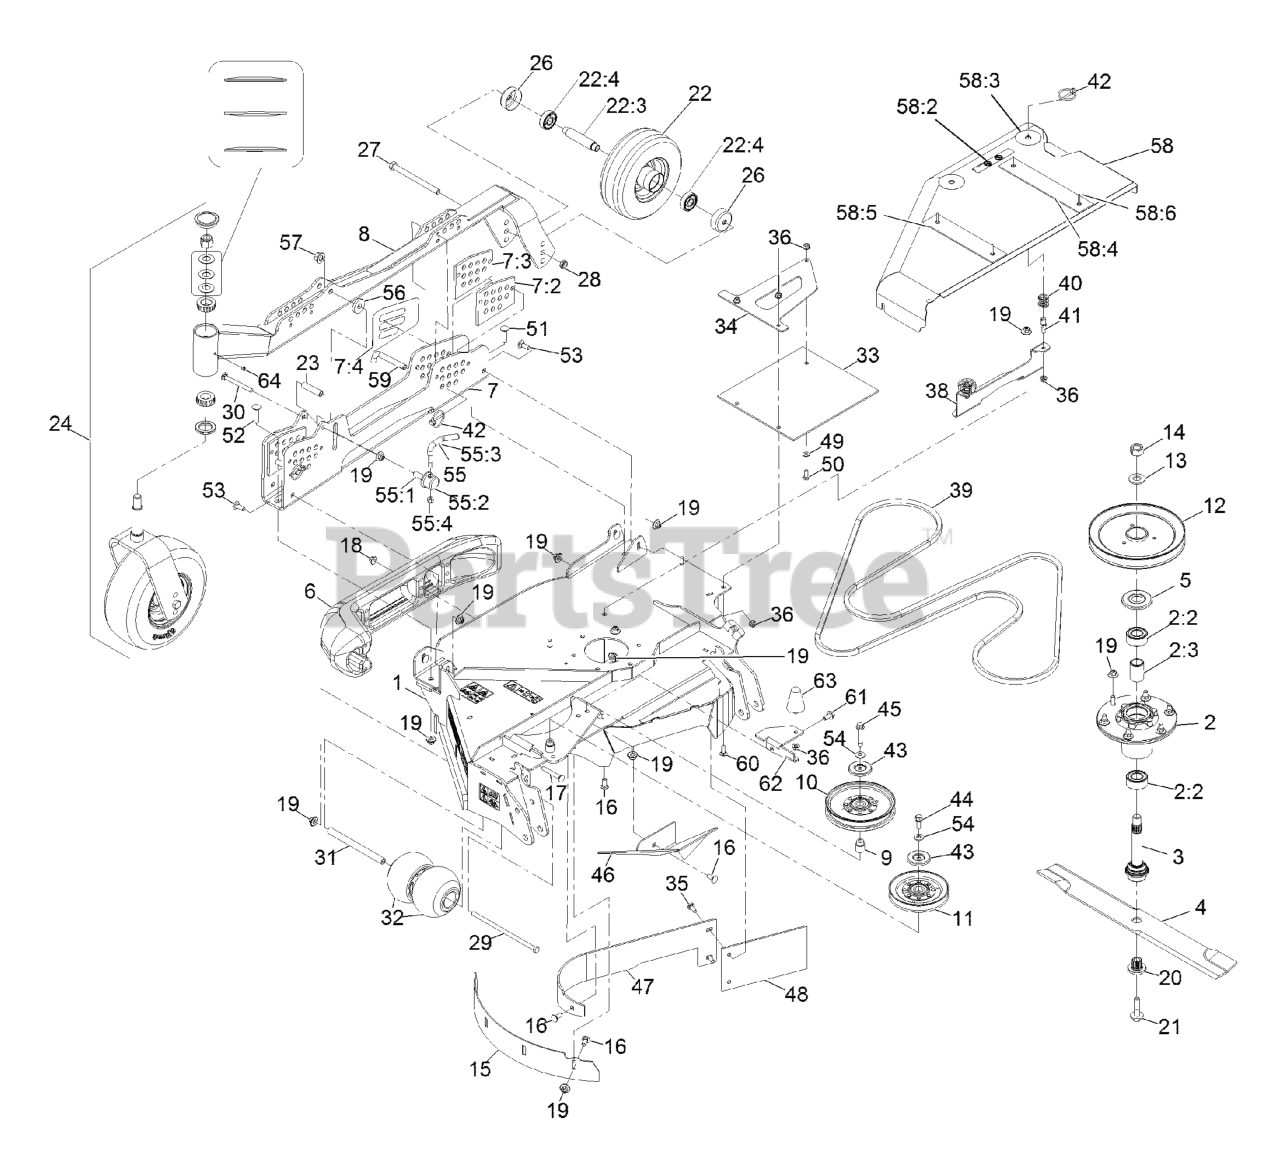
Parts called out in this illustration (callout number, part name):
1	ASM-DECK, RH WING 96
2	ASM-CUTTER HSG
2:2	BEARING-3205 TRASHGUARD
2:3	SPACER-BEARING
3	ASM-SPINDLE AND SEAL
5	GUARD-BEARING, TOP
6	SKID-BUMPER, DECK
7	RH HOC CHANNEL ASM
7:2	PLATE-GUIDE, HOC (LH)
7:3	PLATE-GUIDE, HOC (RH)
7:4	DECAL-HEIGHT OF CUT, RH
8	CALL CUSTOMER SERVICE
9	BUSHING-IDLER
10	IDLER-PULLEY
11	IDLER-V
12	SHEAVE-SINGLE 96RD
14	NUT-HEX
15	BAFFLE-DEPTH, RH
16	BOLT-CARR
17	SCREW-CARR
18	NUT-HF, NI
19	Nut-Nyloc 3/8-16 Flg
20	BUSHING,SPLINED
21	SCREW,SEMS 1/2-20 X 2.19
22	WHEEL AND TIRE ASM
22:3	AXLE-CASTER
22:4	BEARING
26	GUARD, SEAL
27	SCREW-HH
28	NUT-HEX
29	SCREW-HH
30	SCREW-CARR
31	SPACER-WHEEL
32	ROLLER-SCALP, ANTI
33	GUARD-TIRE
34	SUPPORT-FLAP, RH
35	SCREW-CARR
36	NUT-HF, NI
38	BRACKET-SHIELD MOUNT, OUT
41	PIN-SPRING
42	PIN-LYNCH
43	SHIELD-DUST
44	SCREW-HHF 3/8-16 X 1
45	SCREW-HHF
46	BAFFLE-DEFLECT, RH
47	BAFFLE-DOGLEG, RH
48	FLAP-RUBBER
49	WASHER-PLAIN
50	SCREW-HH
51	SCREW-CARR
52	SCREW-CARR
53	BOLT-CARR
54	WASHER-BELLEVILLE
55	LEVER ASM
55:1	SCREW-LOCK
55:2	CAP-LOCK
55:4	NUT-LOCK, NI
57	Nut-Lock 1/2-13
58	ASM-Wing Shield RH
58:2	DECAL-NO STEP
58:3	DECAL-SCRATCH COVER
58:4	Plate-Uhmw 2"
58:5	PLATE-FRONT
58:6	Rivet-Pop
59	PIN-HOC
60	BOLT-CARR
61	SCREW-HWH
62	BRACKET-COVER RETAINER
63	BUMPER-RUBBER
